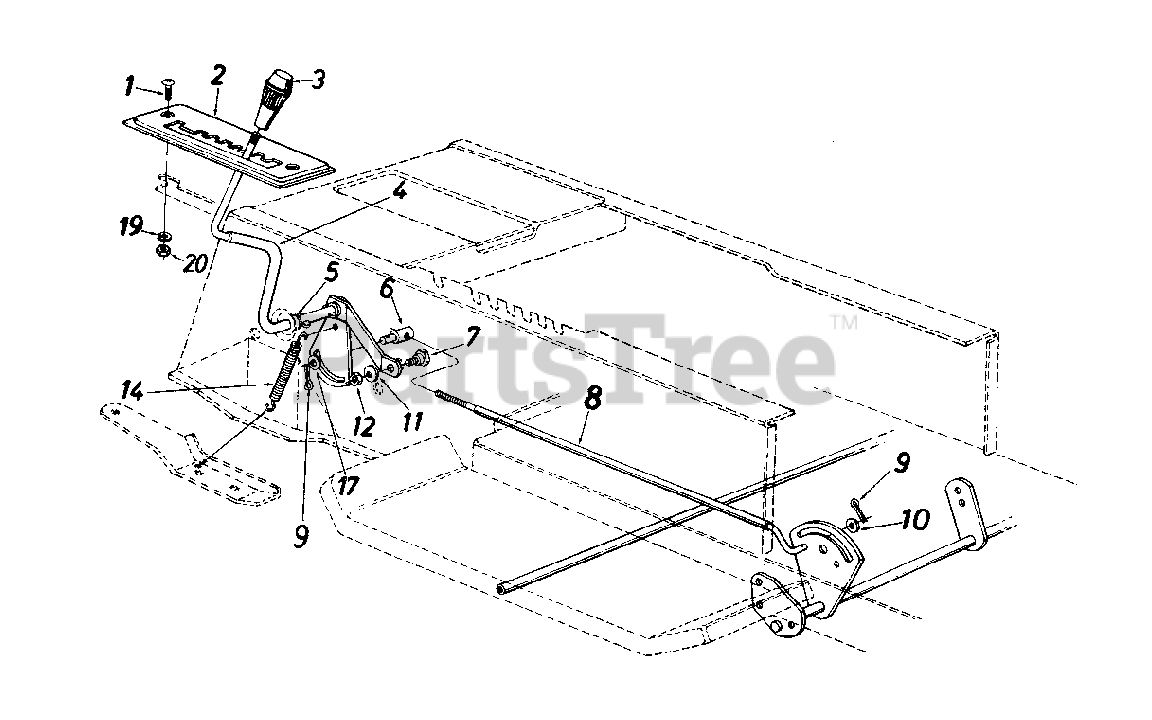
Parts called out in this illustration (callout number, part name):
1	Truss Mach. Scr. 1/4-20 x .75" Lg.
2	8-Speed Selector Plate
4	Speed Selector Lever Ass'y.
5	Flat Washer .53" I.D. x .93"
6	Ferrule 3/8-24 x .37" Dia.
7	Shoulder Bolt
8	Speed Control Link
9	Cotter Pin 3/32" Dia. x 1.0"
10	Fl-Wash. .469" I.D. x .88"
11	L-Wash. 5/16" I.D.
12	Hex Nut 5/16-18 Thd. (Gr. 5)
14	Spring .38" O.D. x 3.18" Lg.
17	Fl-Wash. .385" I.D. x 7/8"
19	L-Wash. 1/4" I.D.
20	Hex Nut 1/4-20 Thd. (Gr.5)
